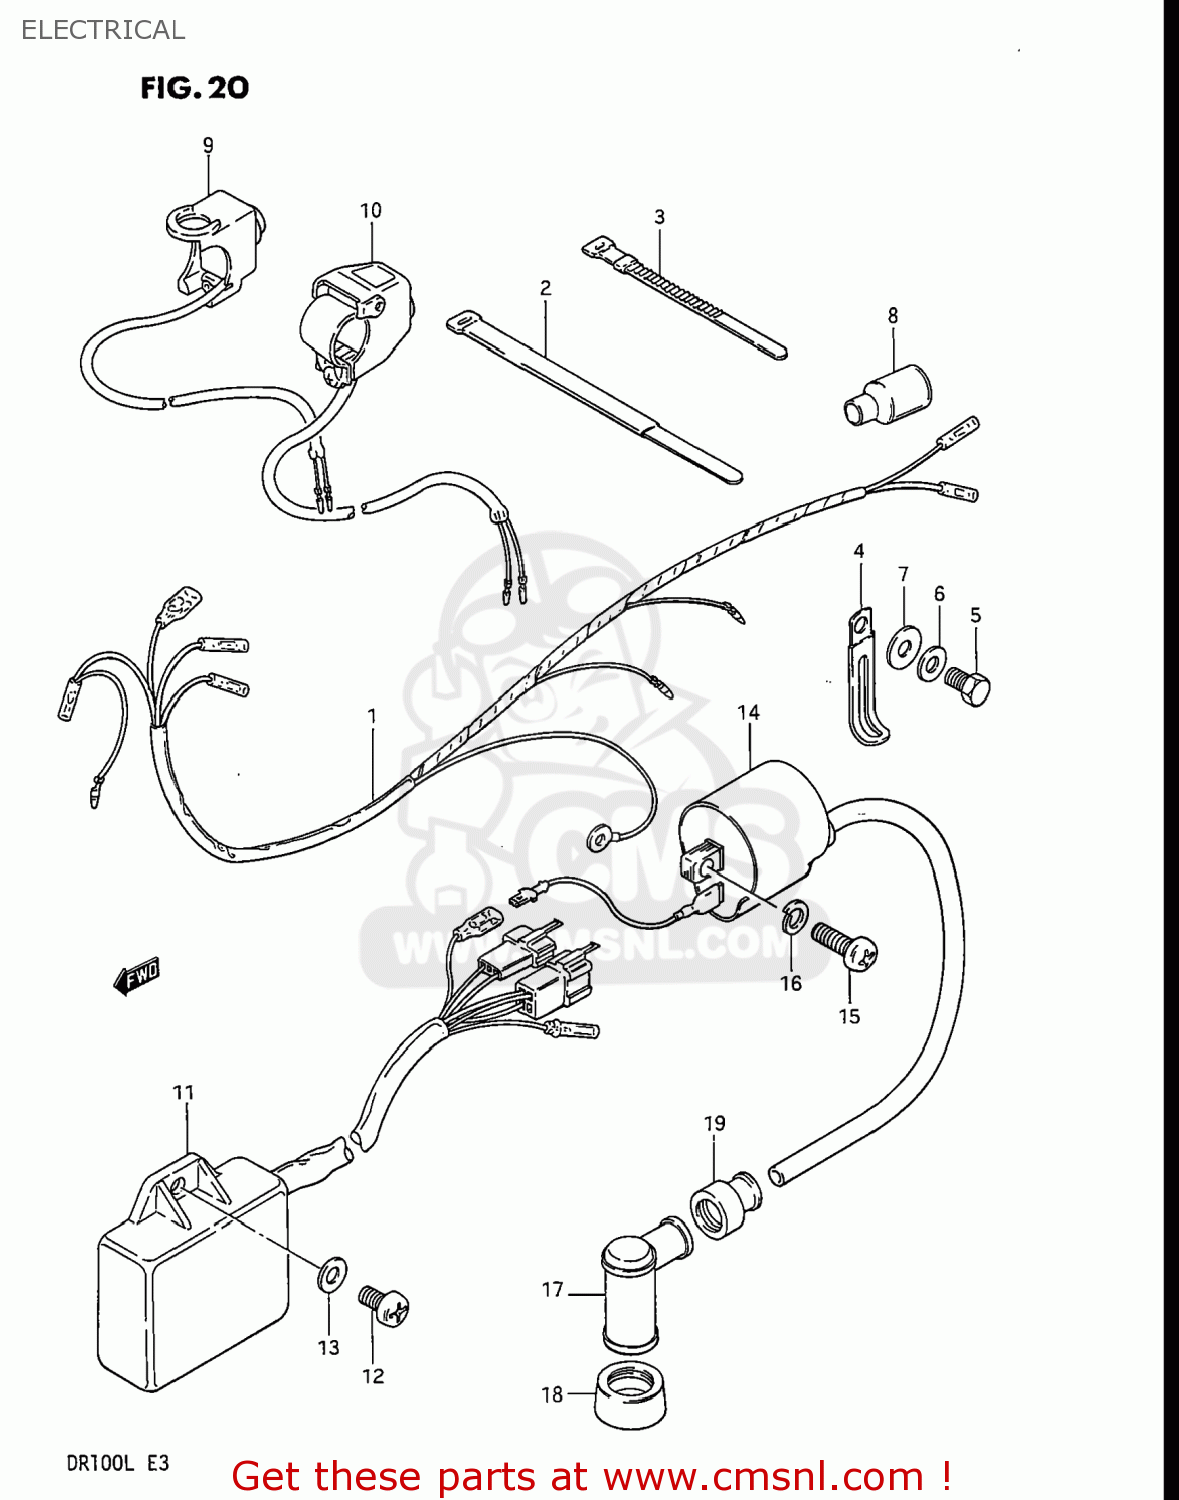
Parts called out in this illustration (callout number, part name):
1	HARNESS,WIRING
2	CLAMP
3	CLAMP(L:120)
4	CLAMP
5	BOLT 6X16
6	WASHER
7	WASHER
8	BOOT,WIRING HARNESS
9	SWITCH ASSY,ENGINE STOP
10	SWITCH ASSY,ENGINE STOP
11	CDI UNIT
12	SCREW
13	WASHER
14	COIL ASSEMBLY,IGNITION
15	SCREW
16	WASHER,LOCK
17	CAP ASSY,SPARK PLUG
18	SEAL,SPARK PLUG CAP
19	SEAL,SPARK PLU
